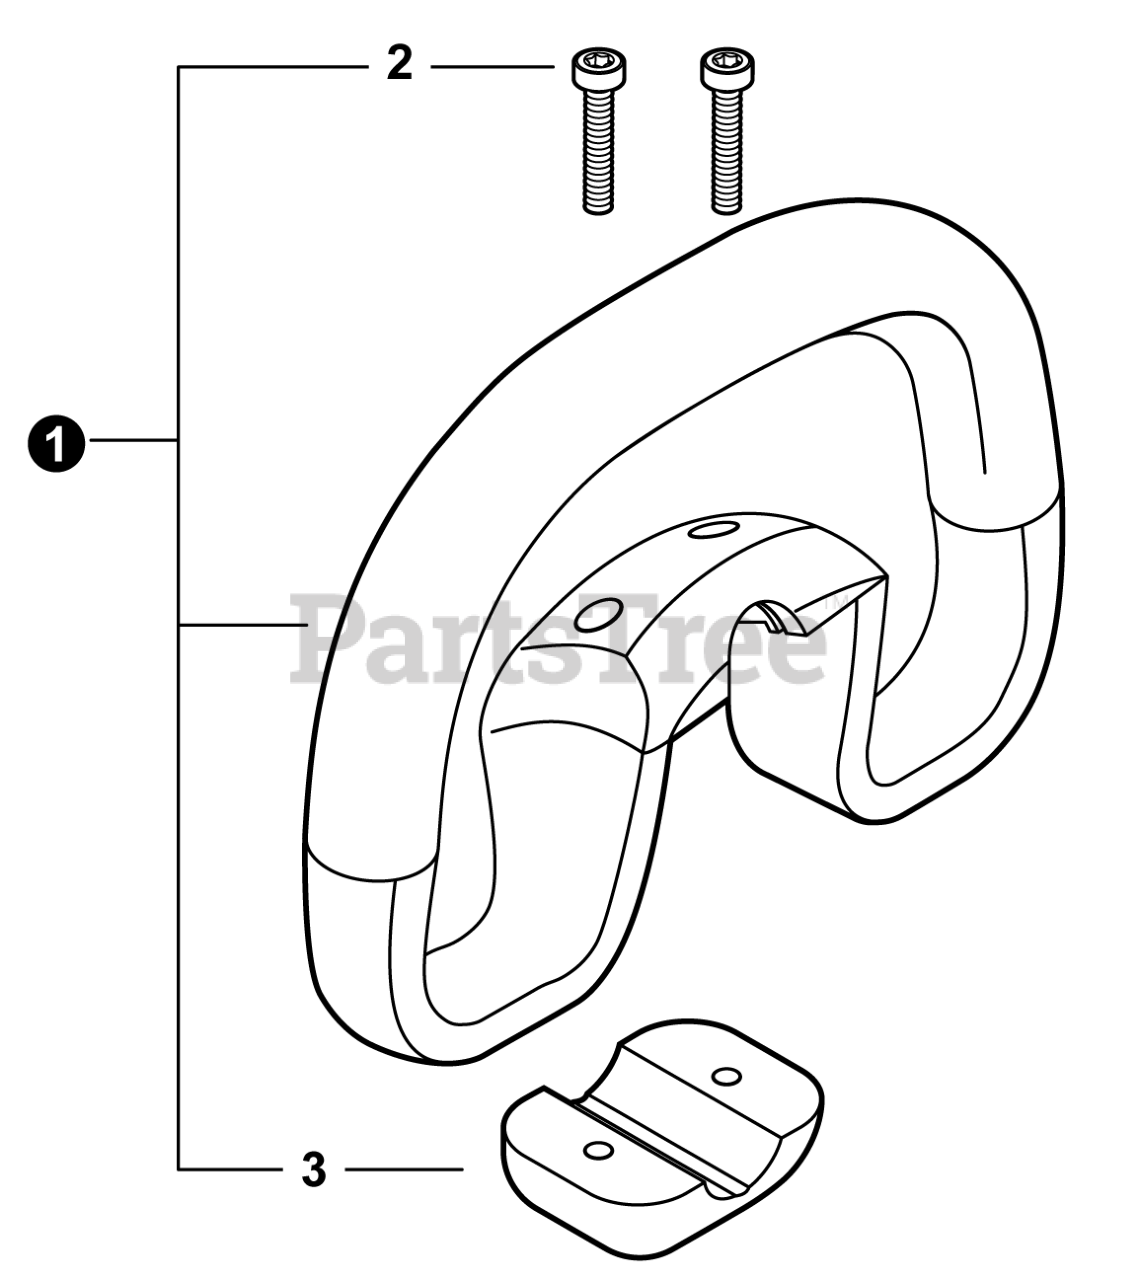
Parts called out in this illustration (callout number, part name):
1	HANDLE ASSY - SUPPORT
2	SCREW 5×40
3	BRACKET, HANDLE
